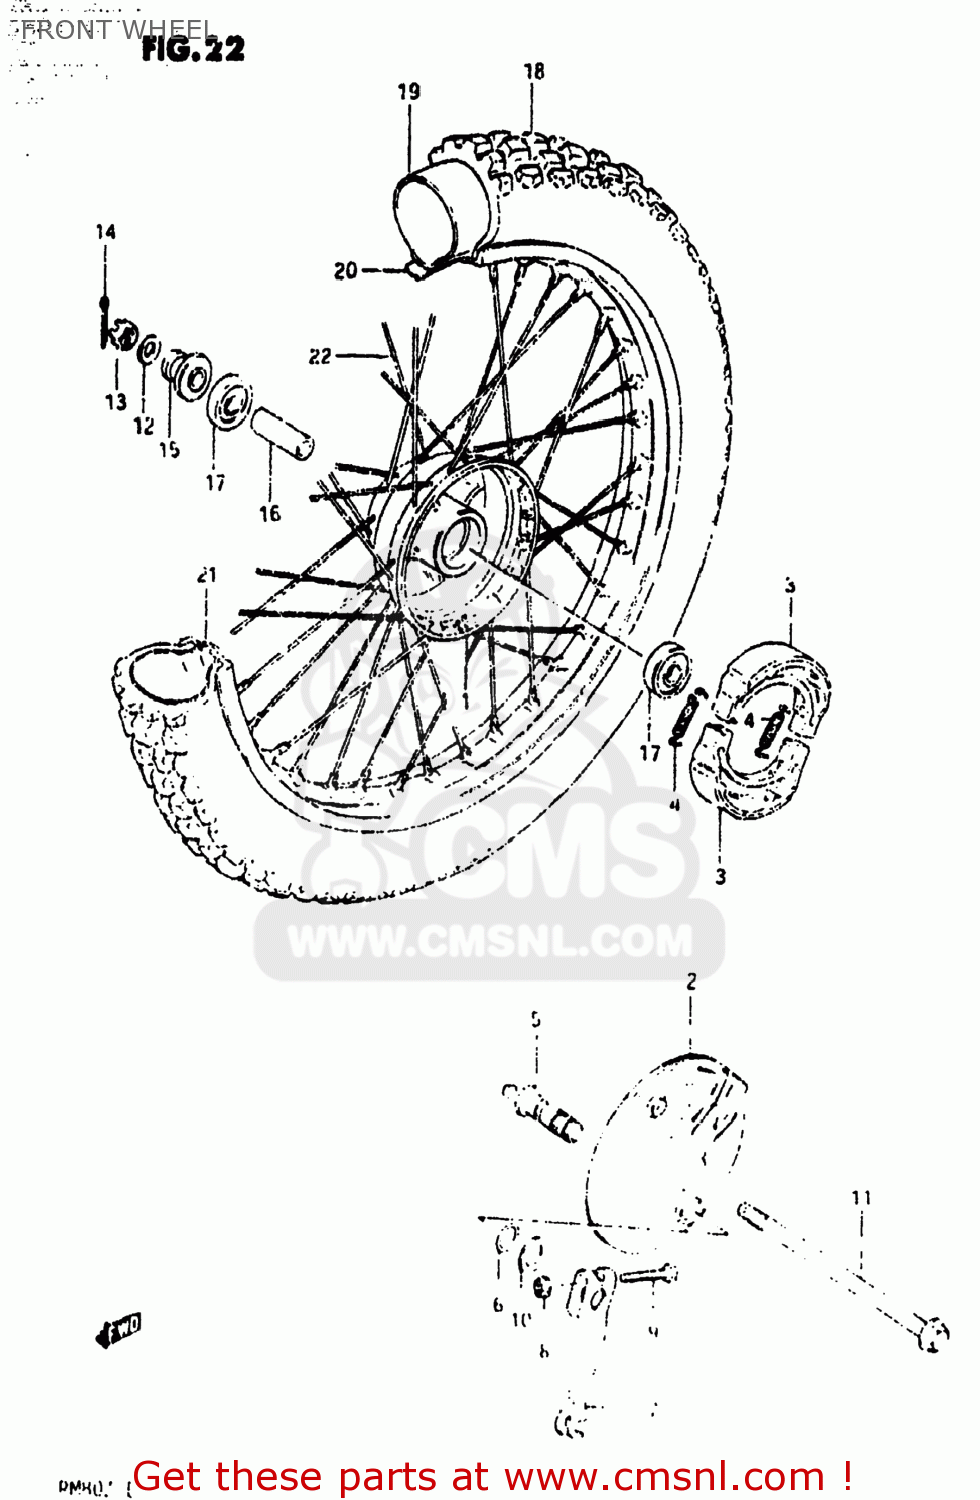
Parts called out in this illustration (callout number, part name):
1	HUB,FRONT
2	PANEL,FRONT HUB
3	SHOE,BRAKE
4	SPRING(L:34)
5	CAM,FRONT BRAKE
6	O RING(D:2.5,ID:11.4)
7	LEVER,FRONT BRAKE CAM
8	NUT
9	BOLT
10	WASHER(12.5X20X1)
11	AXLE,FRONT
12	WASHER
13	NUT
14	PIN 20X20
15	SPACER,FRONT AXLE,RIGHT
16	SPACER (10.4X15X48)
17	BEARING
18	TIRE,FRONT
19	TUBE,INNER
20	PROTECTOR,WHEEL,INNER
21	RIM,FRONT WHEEL
22	SPOKE SET,FRONT
